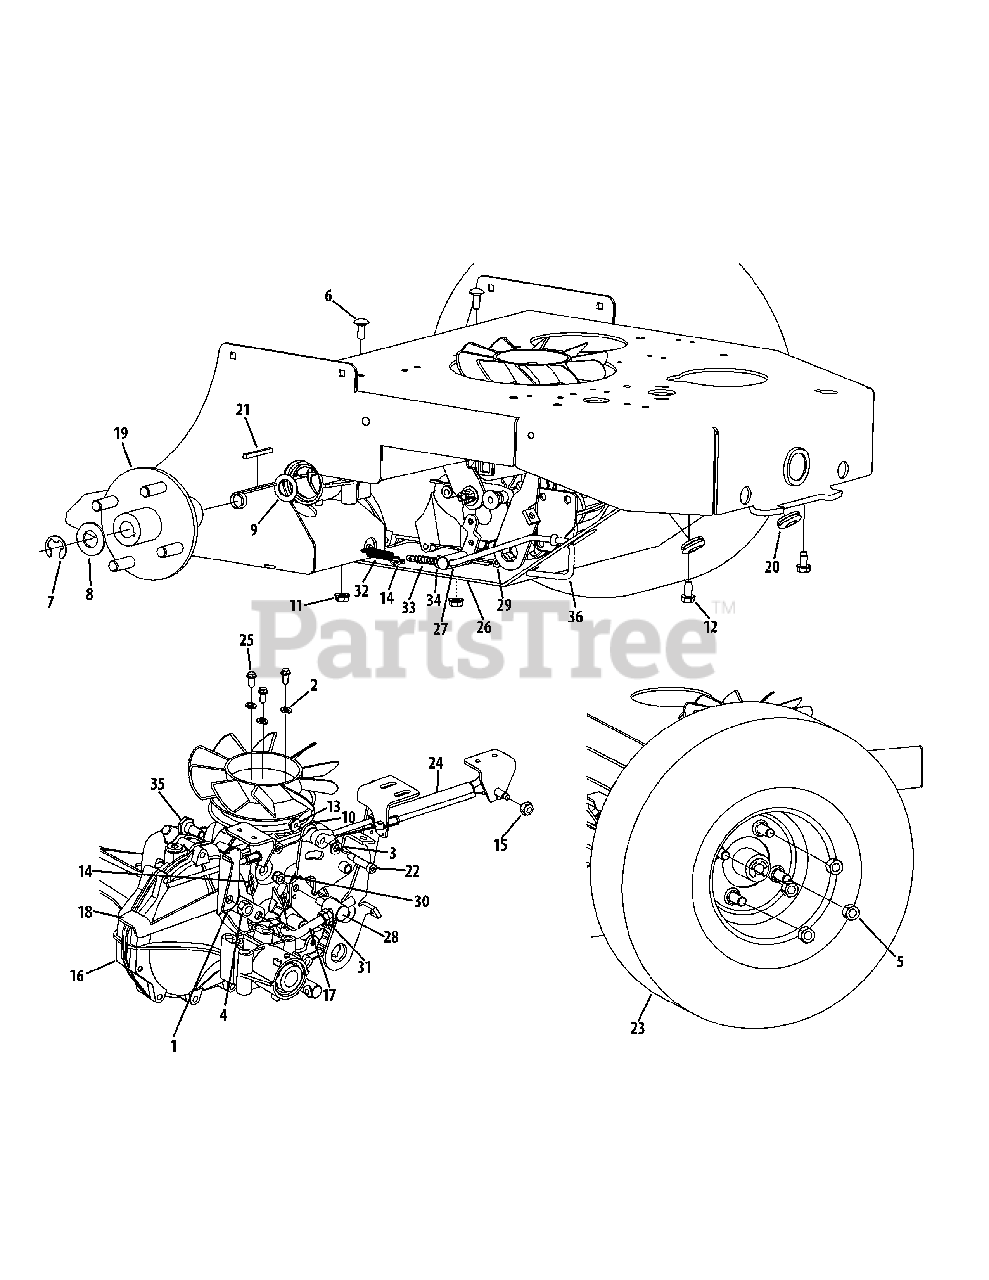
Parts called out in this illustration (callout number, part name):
1	Washer, .563 x 1.38 x .109
2	Lock Washer, 1/4
3	Washer, .344 x .688 x .063
4	Nylock Nut, 3/8-16
5	Lug Nut, 1/2-20
6	Carriage Bolt, 5/16-18 x .75
7	E-Ring, #5133-75
8	Flat Washer, .750 x 1.50 x .120
9	Flat Washer, .06 x .776 x 1.25
10	Flat Washer, 1/4 x .630 x .052
11	Flange Lock Nut, 5/16-18
12	Hex Screw, 5/16
13	Flange Lock Nut, 1/4-20
14	Internal Cotter Pin, .072 x 1.12
15	Hex Nut, M8X
16	Hydro Transmission
17	Brake Lever Rod
18	Brake Lever
19	Wheel Hub Assembly
20	Rubber Grommet, .625 x 1.125
21	Key, 3/16 x 3/16 x 2
22	Shoulder Bolt, 5/16 x 1.00
23	Wheel Assembly, 18 x 6.50-8
24	Damper Assembly
25	Hex Screw, 12-24 x .50
26	Transmission Skid Plate
27	Ferrule, .625 x .25
28	Ferrule, .750 x .313
29	Hex Lock Nut, #10-24
30	Hex Lock Nut, 5/16-18
31	Jam Nut, 3/8-24
32	Extension Spring, .38 x .035 x 2.00
33	Compression Spring, .340 x 1.38
34	Spring Washer, .265 x .562 x .02
35	Shoulder Bolt, .500 x .270 x 3/8
36	Bypass Rod
